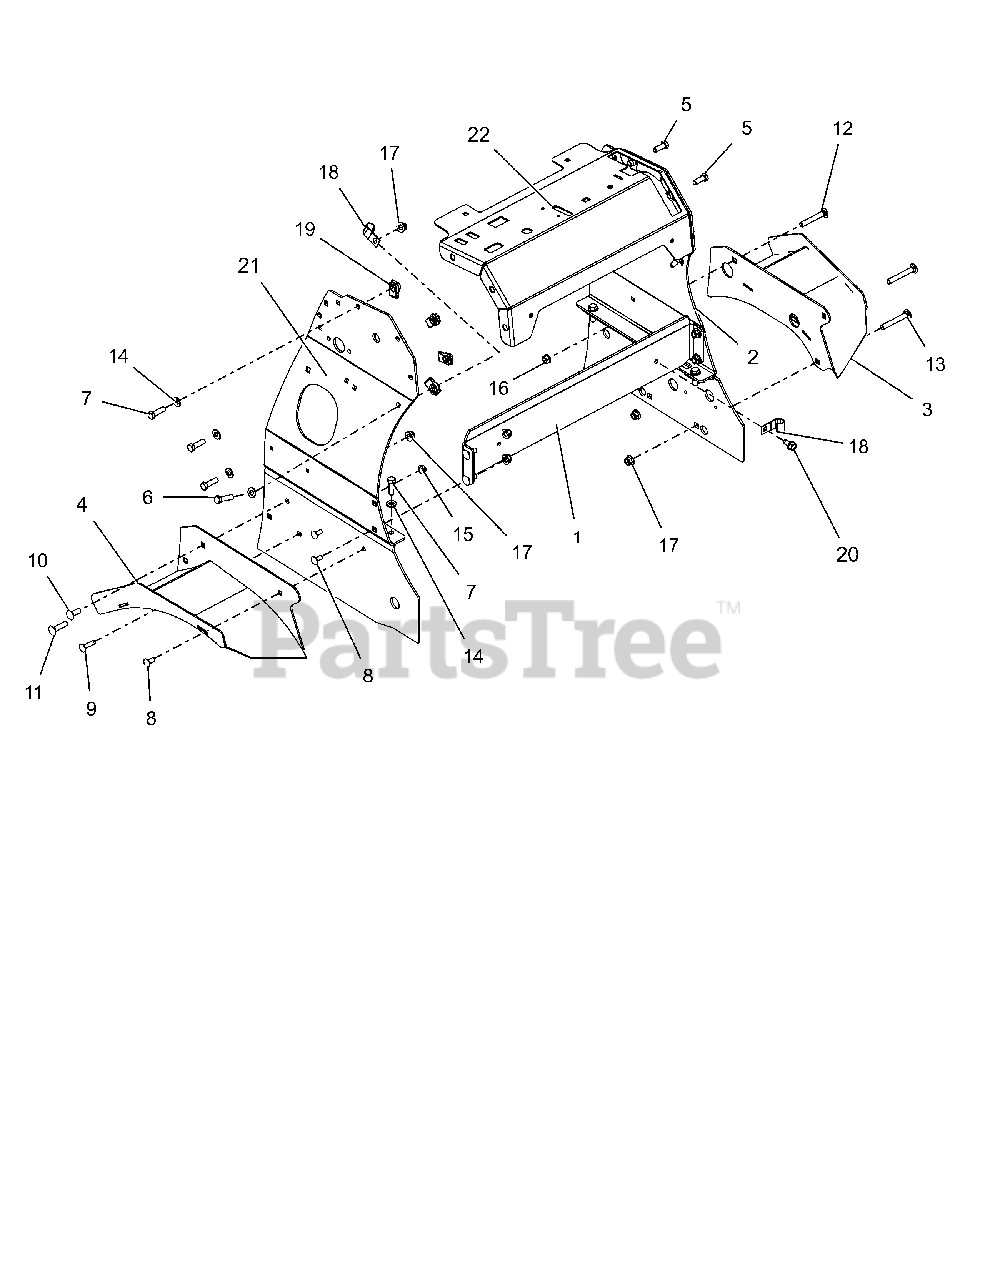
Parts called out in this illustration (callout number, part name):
1	STIFFENER, TOWER
2	PANEL, LH TOWER SIDE
3	WLDMT, LH FENDER
4	WLDMT, RH FENDER
5	@BLT-HEX .38-16X1.00 GR5 YWZC
6	@BLT-HEX .38-16X1.50 GR5 YWZC
7	@BLT-HEX .38-16X1.25 GR5 YWZC
8	@BLT-RDHDSQNK .31-18X.75 G5YZ
9	@BLT-RDHDSQNK .31-18X1.25 G5YZ
10	@BLT-RDHDSQNK .38-16X1.00 G5YZ
11	@BLT-RDHDSQNK .38-16X1.50 G5YZ
12	@BLT-RDHDSQNK .38-16X2.50 G5YZ
13	@BLT-RDHDSQNK .38-16X2.75 G5YZ
14	@WSHR-FL-STL.406X.812X.065 YWZ
15	@NUT-SPNLK-FLG .312-18 YWZC
16	@NUT-LK-TOP-FLG .38-16 YWZC
17	@NUT-LK-NYL-FLG .38-16 YWZC
19	NUT-RTNR .375-16X.37
20	@SCR-TAP .38-16X.75 HWH TR YWZ
21	KIT, SERVICE RH TOWER
22	KIT, 48-60 PS DASH WITH DECAL
